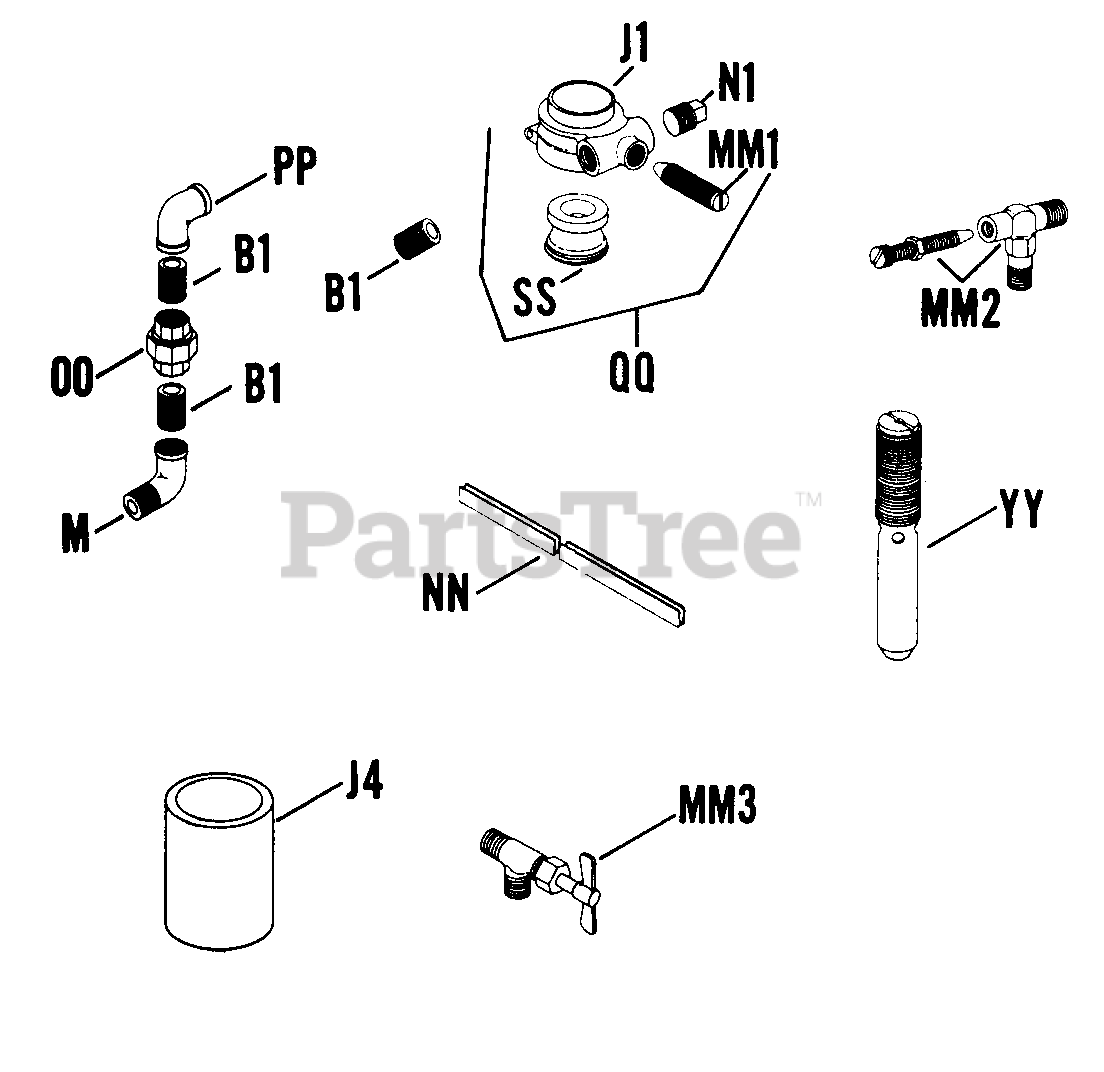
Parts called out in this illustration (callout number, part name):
B1	PIPE - USE 46 136 01
M	ELBOW - USE 47 283 02
N1	PLUG,PIPE 1/2 NPTF SQUARE HD USE 25 139 61-S
MM1	VALVE - DISCONTINUED
QQ	ADAPTER - DISCONTINUED
SS	VENTURI - DISCONTINUED
